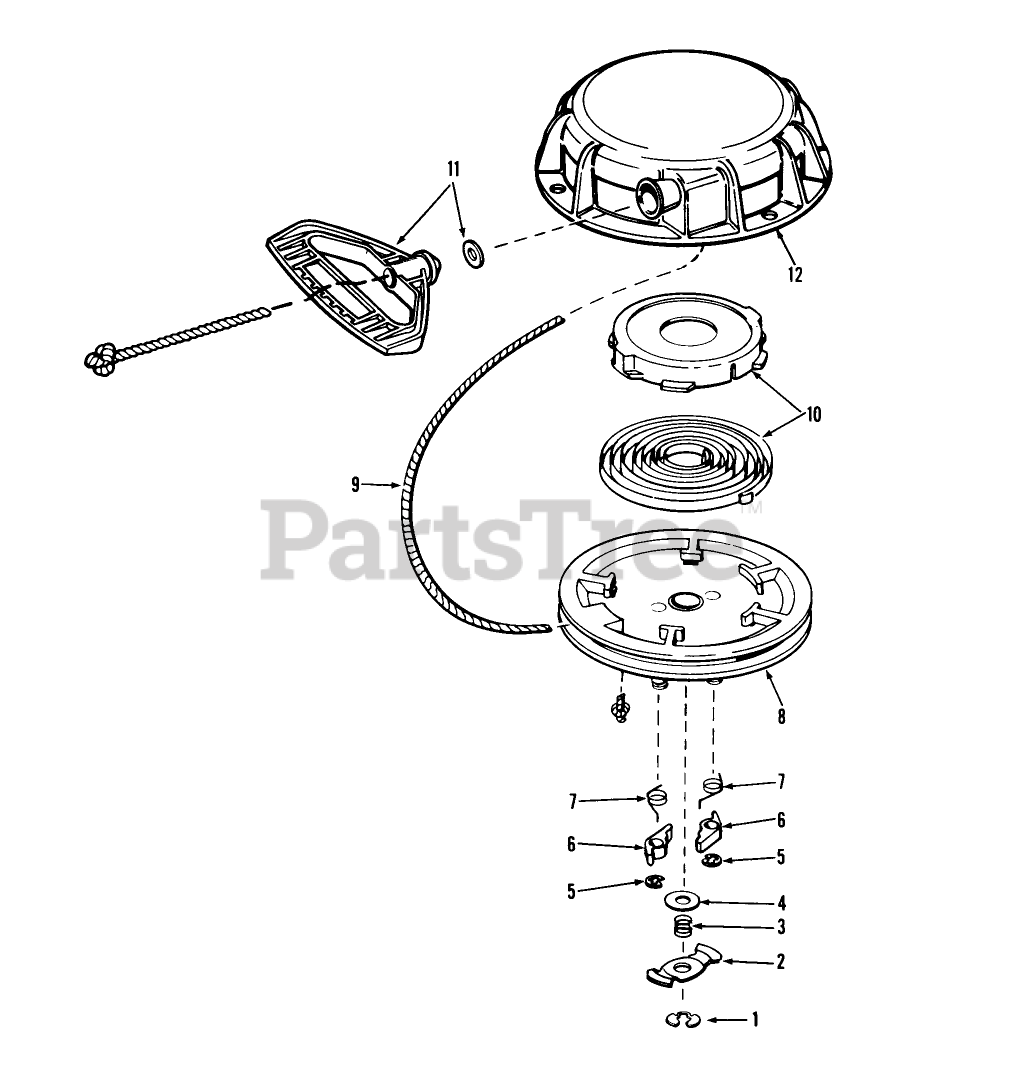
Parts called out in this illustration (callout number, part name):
1	Ring-Retaining
2	Cam, Dog
3	Spring, Brake
4	Washer-Thrust
5	Ring, Retainer
7	Spring, Dog
8	Pulley
9	Rope-Starter
10	Spring Keeper Assy.
11	Handle-Starter, Mitten Grip
12	Housing Assy., Starter
